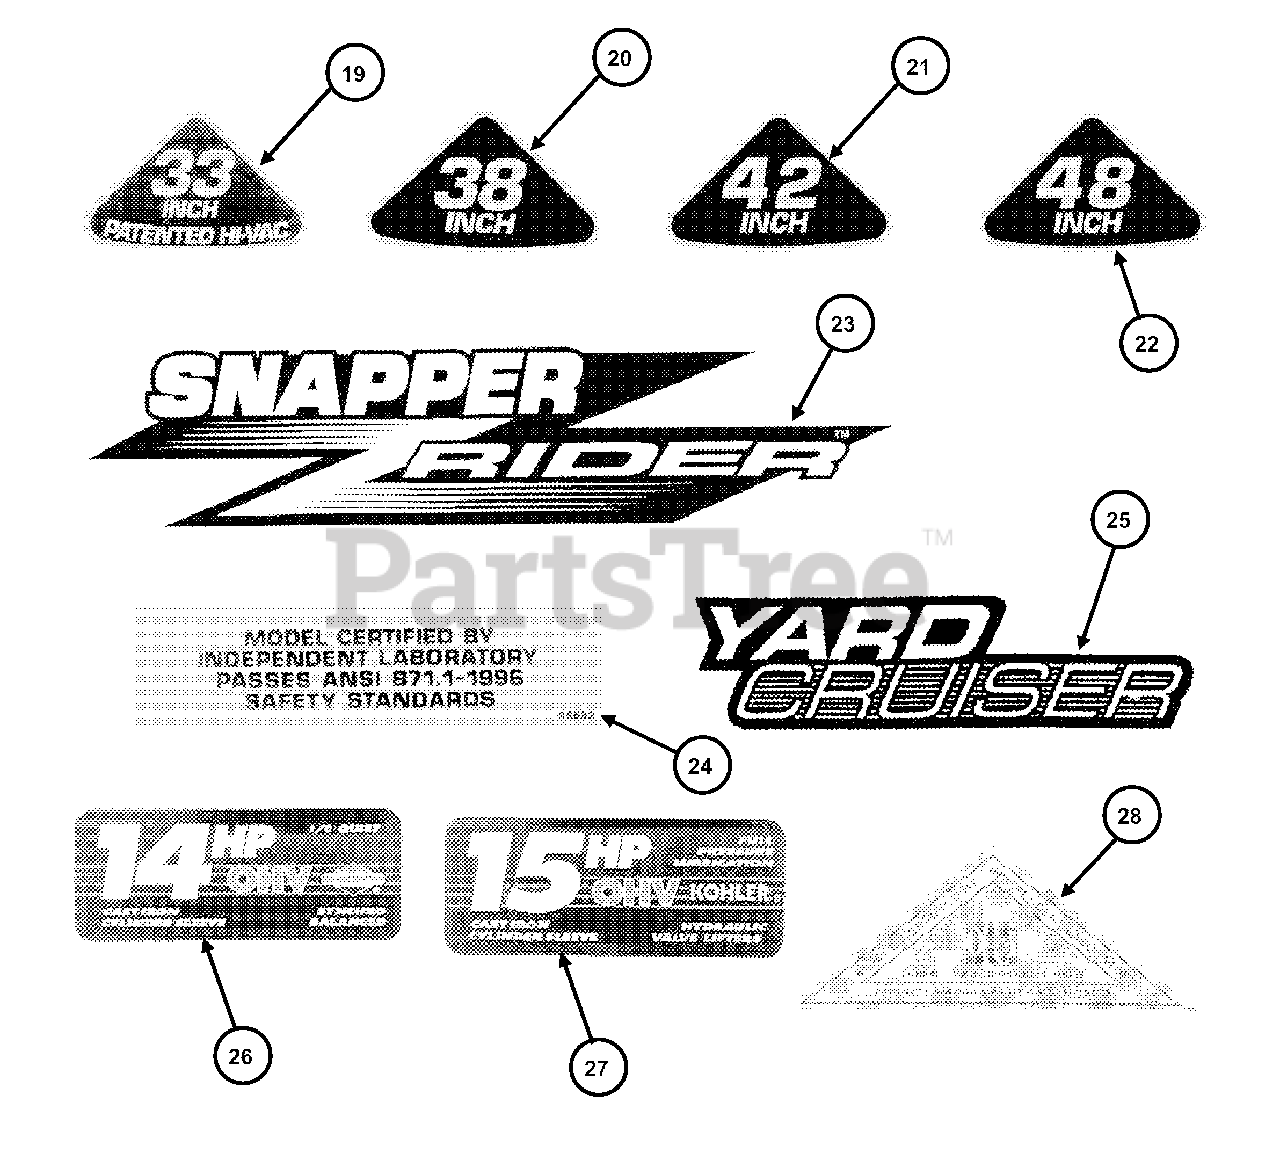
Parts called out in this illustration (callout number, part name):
19	DECAL, 33" Hi-Vac Deck
20	DECAL, 38" Deck
21	DECAL, 42" Deck
22	DECAL, 48" Deck
23	DECAL, SNAPPER Z-Rider (Steel Bodied Models)
24	DECAL, Certification
25	DECAL, Yard Cruiser
26	DECAL, Briggs 14HP Engine
27	DECAL, Kohler 15HP Engine
28	DECAL, OPEI Ride-On
